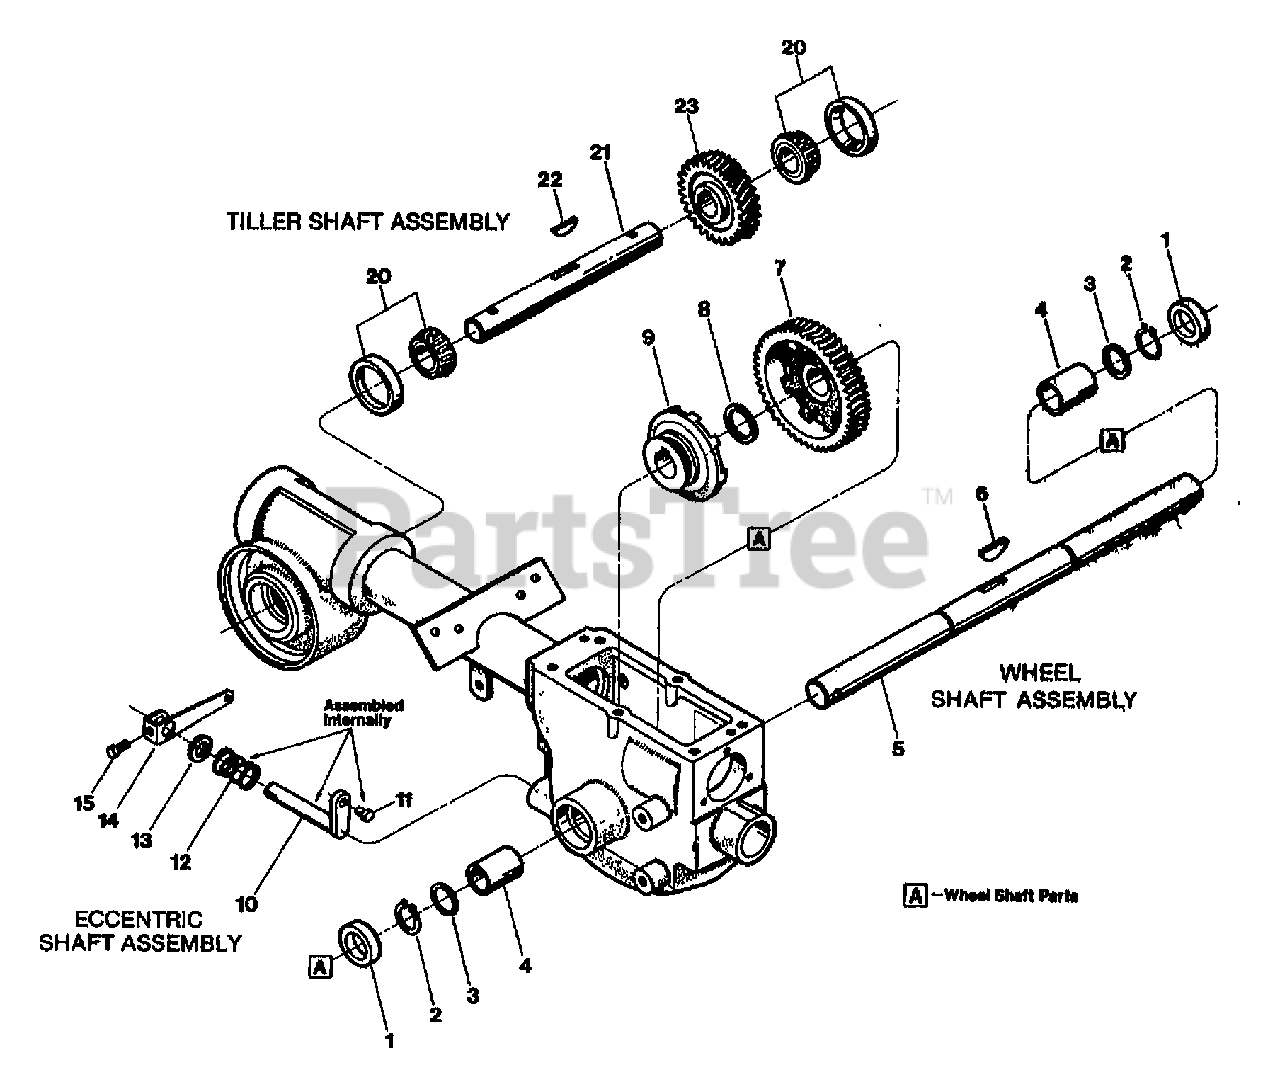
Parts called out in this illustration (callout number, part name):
1	SEAL-OIL WHEELSHAFT
2	RING-HEAVY EXT .906 ID
3	SHIM-1.375X1.015X.062
3	SHIM-1.375X1.015X.03
3	SHIM-1.375X1.015X.015
3	SHIM-1.375X1.015X.01
4	BUSHING-1.25X1.005X1.5
5	WHEELSHAFT W/KEY
6	KEY-HI PRO .25X1.312
7	GEAR-WORM 46 TEETH MACH
8	WASHER-1.468X1.016X.062
9	CLUTCH-MACH
10	WELD-ECCENTRIC
11	PIN-.375 X .72
12	SPRING-.850 X .875 LONG
13	SEAL-OIL ECCENTRIC
14	LEVER-CABLE ADJ PNT
15	SCR-HH 1/4-20X.5 GR5 YEL
20	BEARING CUP & CONE (W/RACE)
21	SHAFT W/KEY (TILLER)
22	KEY-WOODRUFF .25X1.12
23	GEAR-TILLER MACH
